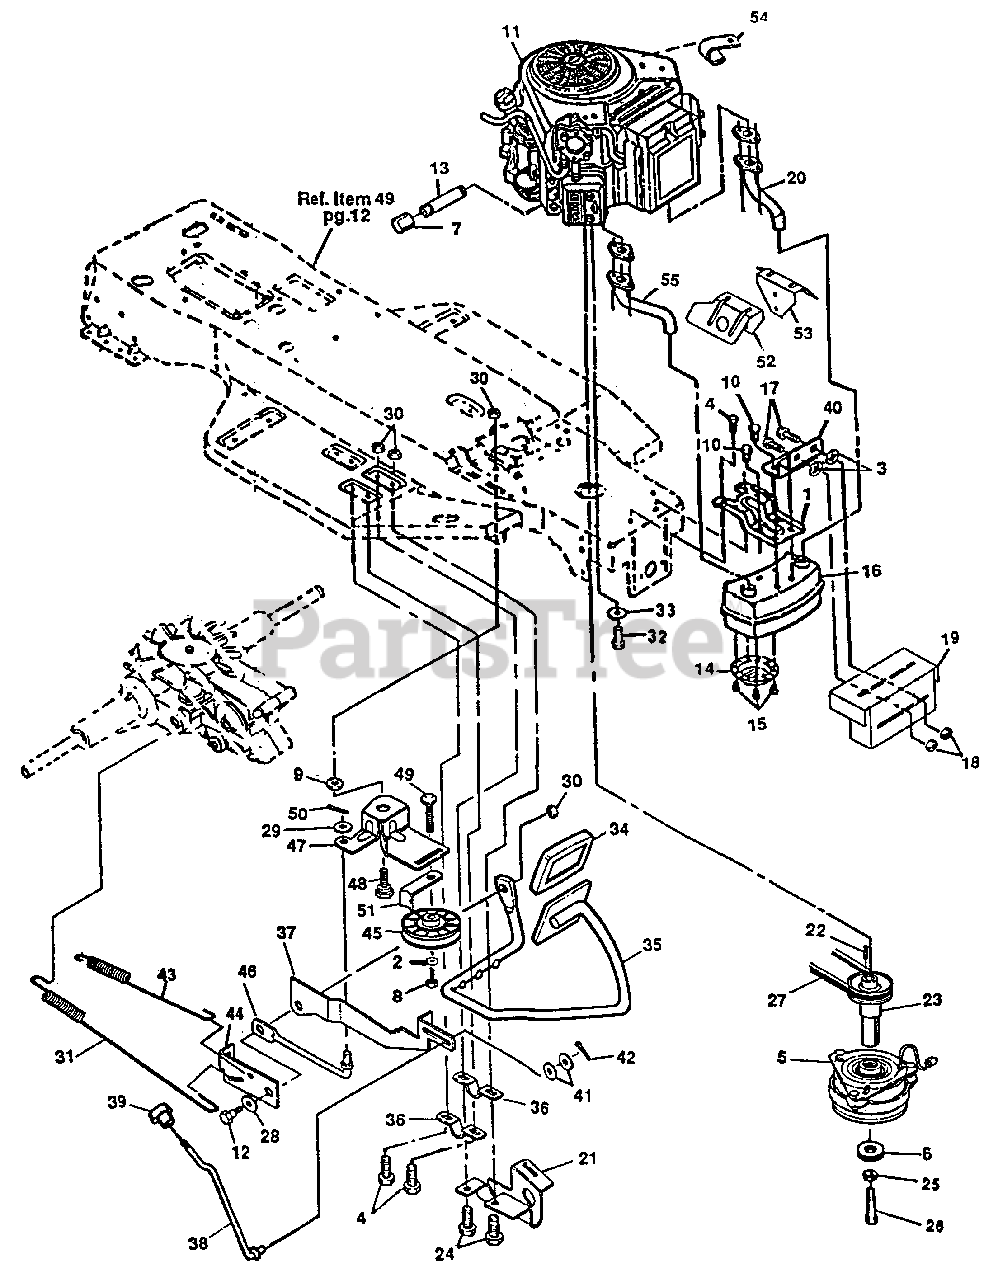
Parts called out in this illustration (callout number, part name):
1	Muffler Bracket
2	Washer, Reg. Split Lock
3	Pushnut, 5/16 Bolt Retainer
4	Screw, 5/16-18 x 1/2
5	Electric Clutch
6	Bearing, Sleeve Sector Gear
7	Pipe Cap
8	Nut, 3/8-16 Thd.
9	Flatwasher, .333 x .87 x .119
10	Screw, 1/4-20 x 5/9 In.
11	ENGINE
12	Bolt, Shoulder 5/16-18
13	Nipple, 3/8-18
14	Deflector Side Out
15	Screw, #8-32 x .3/8
17	Bolt, 5/16-18x5/8
18	Nut, 5/16-18
19	Heat Shield
20	Tube, Muffler Exhaust, L.H.
21	Bracket, Front Hanger
22	Key, Square
23	Engine Pulley Assembly
24	Screw, 5/16-18 x 3/4 In.
25	Lockwasher, .459 x .78 x .12
26	Screw, 7/16-20 x 51/2 In.
27	Hydro Traction Belt
28	Wave Washer
29	Flatwasher, .406 x .81 x .06
30	Nut, 5/16-18
31	Spring, Hydro Brake
32	Screw, 7/16-20 x 51/2 In.
33	External Lockwasher
34	Clutch Brake Pad
35	Clutch Brake Weld Assy.
36	Clutch Brake Arm Bracket
37	Park Brake Lever
38	Parking Brake Rod
39	Knob, Parking Brake
40	Transaxle Brkt.
41	Flatwasher, .250 x .56 x .04
42	Cotter Pin
43	Electric Clutch Spring
44	Bracket-Brake, Neutral
45	Idler Pulley
46	Clutch Rod
47	Idler Arm
48	Bolt, Shoulder, 5/16-18
49	Screw, 3/8-16 x 1-1/2 In.
50	Cotter Pin
51	Retainer Belt
52	Air Deflector
53	Air Deflector
54	Wire Retainer
55	Tube, Muffler Exhaust R.H.
